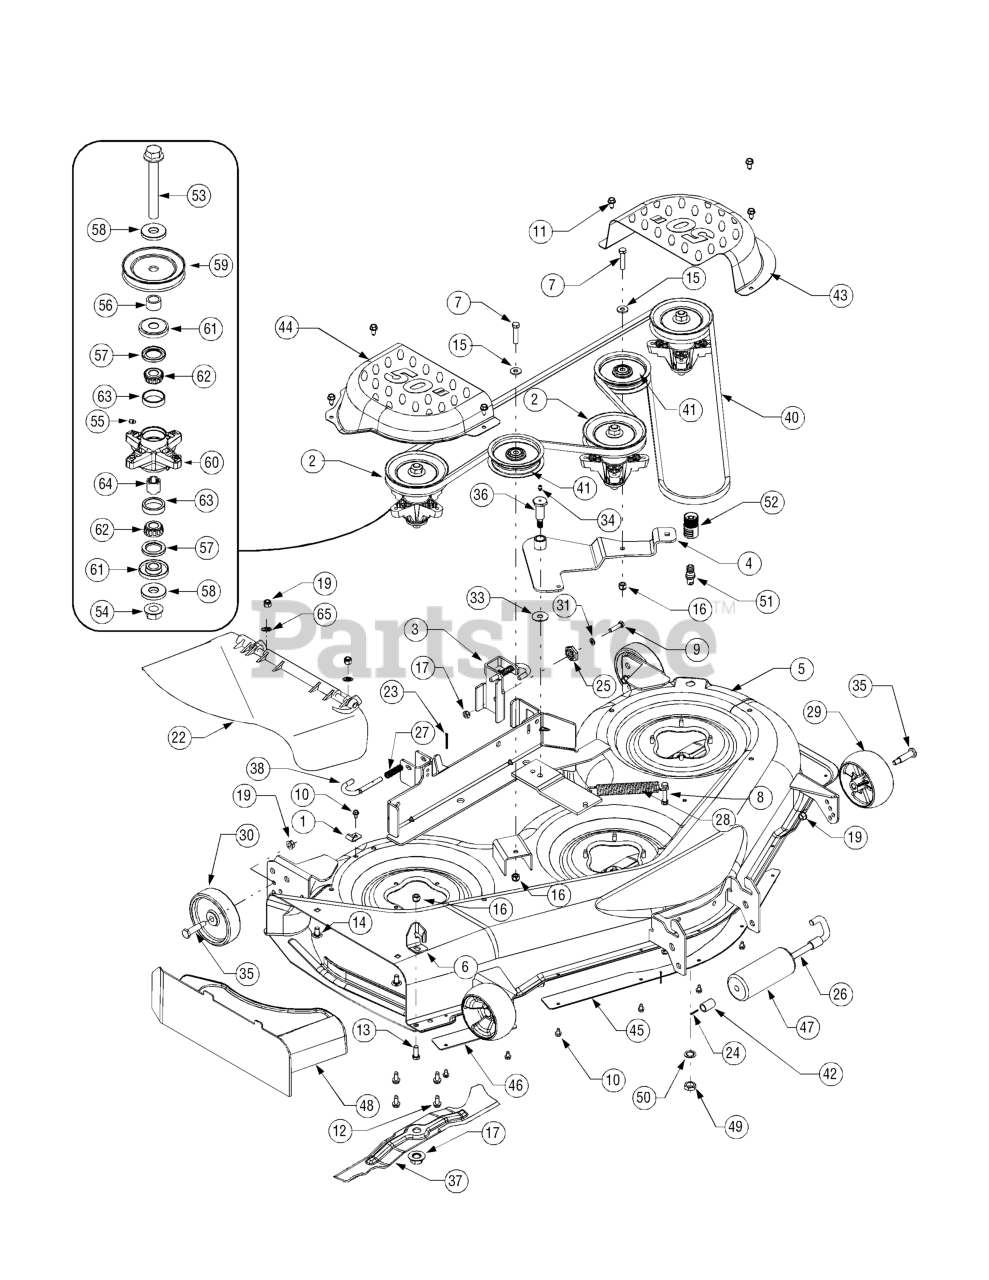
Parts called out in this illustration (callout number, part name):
1	Hook, Retainer
2	Spindle Assembly
7	Screw, 3/8-16, 1.75
8	Screw, 5/16-18 x 2.00
9	Screw, 5/16-18, 1.25, Gr5
10	Screw, 1/4-20 x 0.5
11	Screw, 5/16-18 x.625
12	Screw, 5/16-18 x .75
13	Screw, 3/8-16 x 1.0
14	Screw, Carriage, 3/8-16 x .75
15	Washer, Flat, .406 x .875 x .059
16	Nut, Nylon Lock, 3/8-16
17	Nut, Hex, Flange, 5/8-18
18	Nut, Nylon Lock, 5/16-18
19	Nut, Flange Lock, 3/8-16
20	Nut, Hex, 5/16-18, Gr5
21	Nut, 7/16-14
22	Chute Assembly, Side Discharge
23	Pin, Cotter, 1/8 x 1.25
24	Pin, Cotter, 3/32 x 1.25
25	Deck Adjustment Gear
26	Roller Pin
27	Spring, Compression, .531 x 1.75
28	Spring, Extension, .94 x 6.74
29	Deck Wheel, 5.0
30	Deck Wheel, 5.0
31	Washer, Lock, 5/16
32	Washer, Bell, .45 x 1.0 x .062
33	Washer, Flat, .442 x 1.38 x .060
34	Fitting, Lube, 3/16
35	Shoulder Screw .498 x 1.53 x 3/8-16
35	Shoulder Bolt, .50 x 2.5 x 3/8-16
36	Screw, Shoulder, .68 x 1.59
37	Blade
38	Rod, Deck Release .375 Dia
39	Spacer, .550 x .755 x 1.1
40	Belt, V-Type, Aramid, B Sec. X 134
41	Pulley, Idler, 3.5"
42	Spacer, 1.1"
48	Baffle, Mulch
49	Nut, Hex, M16-1.5
50	Washer, Lock
51	Port, Water
52	Coupler, Hose
53	Bolt, Spindle, 3/4-16, 5.85
54	Nut, Flange Lock, 3/4-16
55	Lube Fitting, 3/16
56	Spacer, .730
57	Seal, Oil
58	Spacer, Blade
60	Housing, Spindle with bearings and seals
61	Spacer, Spindle
62	Cone Bearing, Tapered Roller,
63	Cone Cup, Tapered Roller, .750
64	Spacer, Bearing, .780 x 10 x
